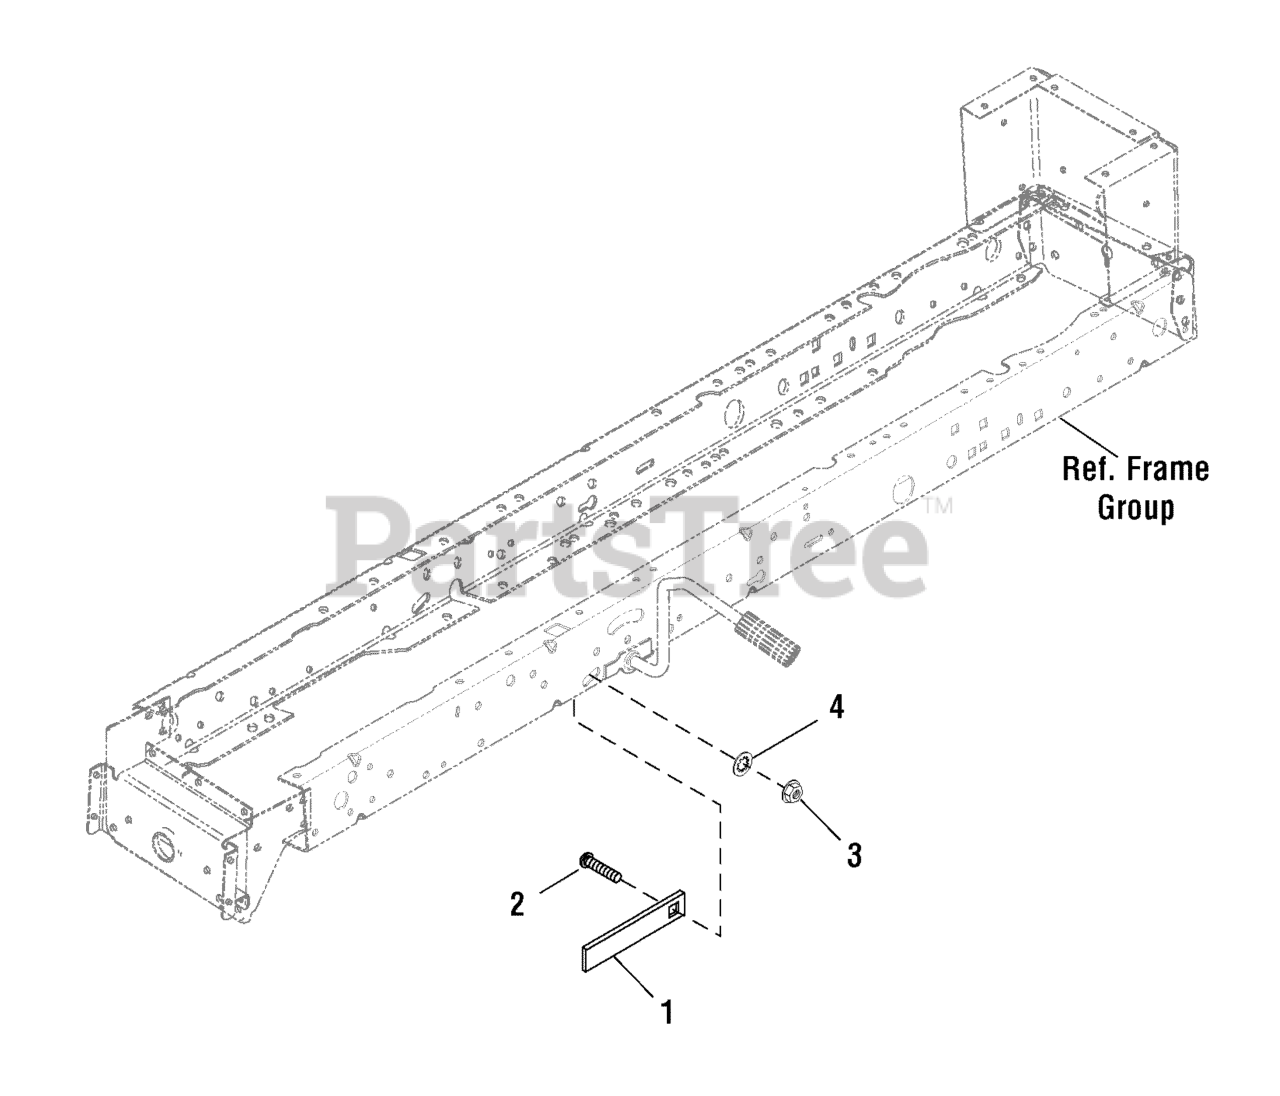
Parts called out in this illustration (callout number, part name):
1	STOP, Steering
2	BOLT, Carriage, Short Neck, 5/16-18 x 1
3	NUT, Hex Flange, Serrated Lock, 5/16-18
4	RETAINER, Push, 5/16-18
